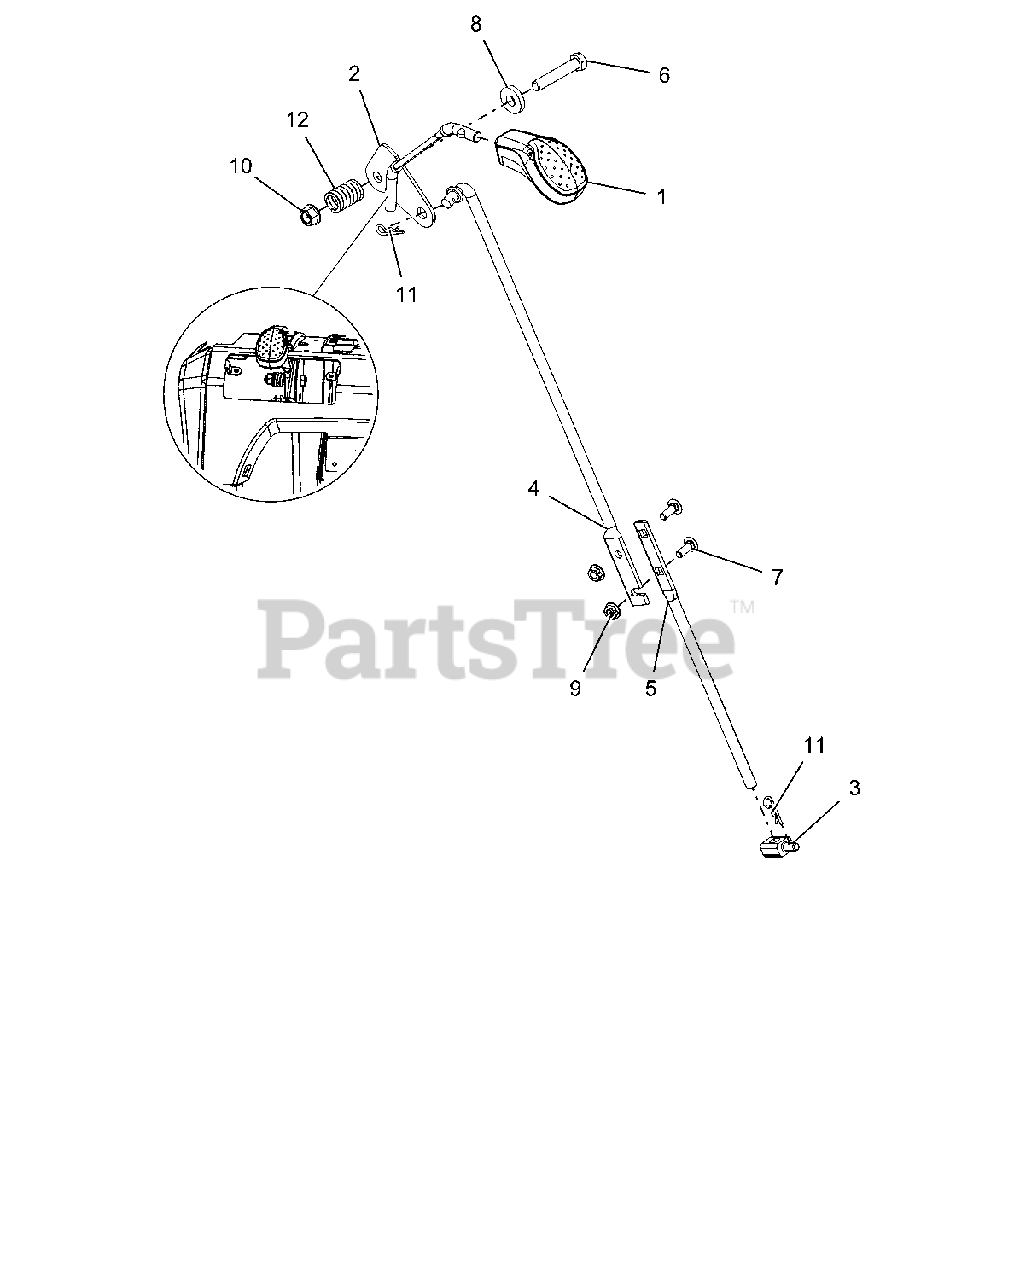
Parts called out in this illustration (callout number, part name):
1	KNOB, CONTROL, DASH
2	WELDMENT,LG DASH SPEED CONTROL
3	PIVOT,SHIFT ROD .375-16(TRUNN)
4	ROD, SHIFT - UPPER
5	ROD, SHIFT - LOWER
6	@BLT-HEX .38-16X2.00 GR5 YWZC
7	@BLT-RDHDSQNK .25-20X.75 G5YZ
8	WSHR-FL-STL .406X1.00X.188 YWZ
9	@NUT-LK-CTR-FLG .25-20 YWZC
10	@NUT-LK-TOP-FLG .38-16 YWZC
11	PIN-HAIR INT .08X.18X1.18 YWZC
12	SG-COMP .125X.781X1.250
